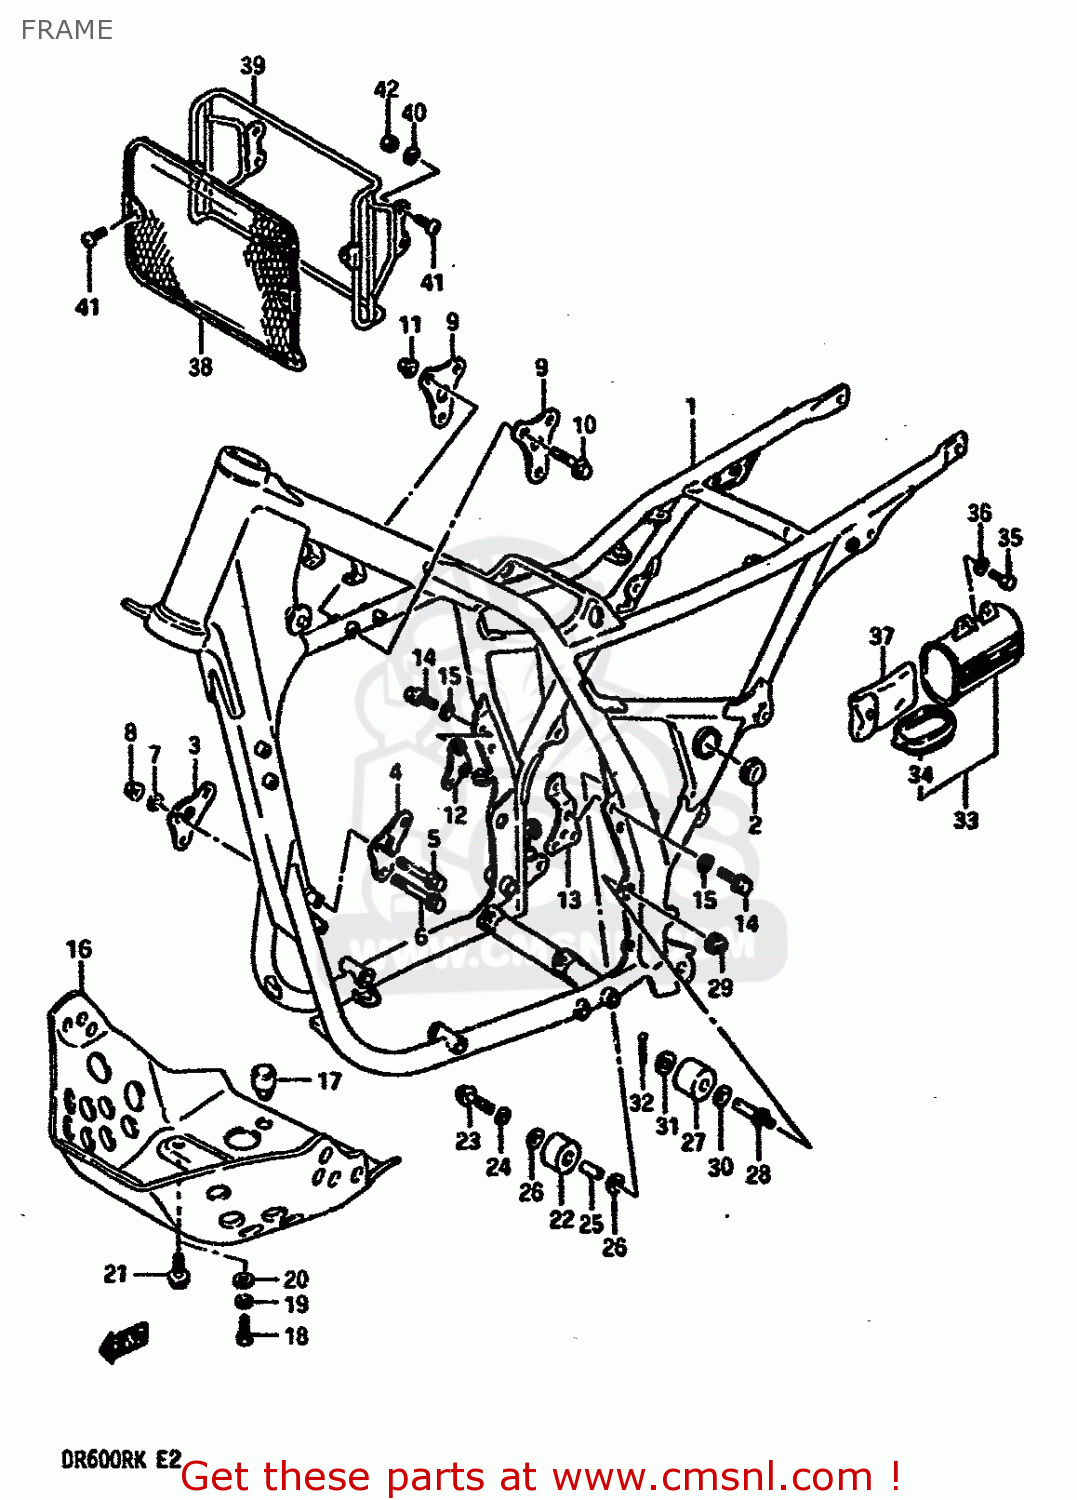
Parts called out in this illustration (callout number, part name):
1	FRAME (BLUE)
2	CAP, CUSHION LEVER (BLUE)
3	PLATE,ENGINE MOUNTING,FRONT
4	PLATE,ENGINE MOUNTING,FRONT
5	BOLT(8X67)
6	BOLT(8X75)
7	WASHER,LOCK
8	NUT
9	PLATE,ENGINE MOUNTING,UPPER
10	BOLT
11	NUT
12	PLATE,ENGINE MOUNTING,REAR
13	PLATE,ENGINE MOUNTING,REAR
14	BOLT
15	WASHER,LOCK
16	PROTECTOR,ENGINE
17	CUSHION
18	BOLT
19	WASHER,LOCK
20	WASHER (6.5X24X1.2)
21	BOLT 8X16
22	ROLLER,CHAIN CONTROL
23	BOLT 8X40
24	WASHER,LOCK
25	SPACER(8.6X12X25.5)
26	WASHER
27	ROLLER,CHAIN LENGTH CONTROL
28	BOLT,CHAIN LENGTH CONT LWR
29	NUT
30	WASHER
31	WASHER
32	PIN 25X20
33	HOLDER,TOOL
34	CAP,HOLDER
35	BOLT 6X16
36	WASHER (6.5X18X1.6)
37	TOOL ASSY
38	GUARD, HEADLAMP
39	BRACE, HEADLAMP GUARD
40	WASHER
41	SCREW 6X12
42	NUT
